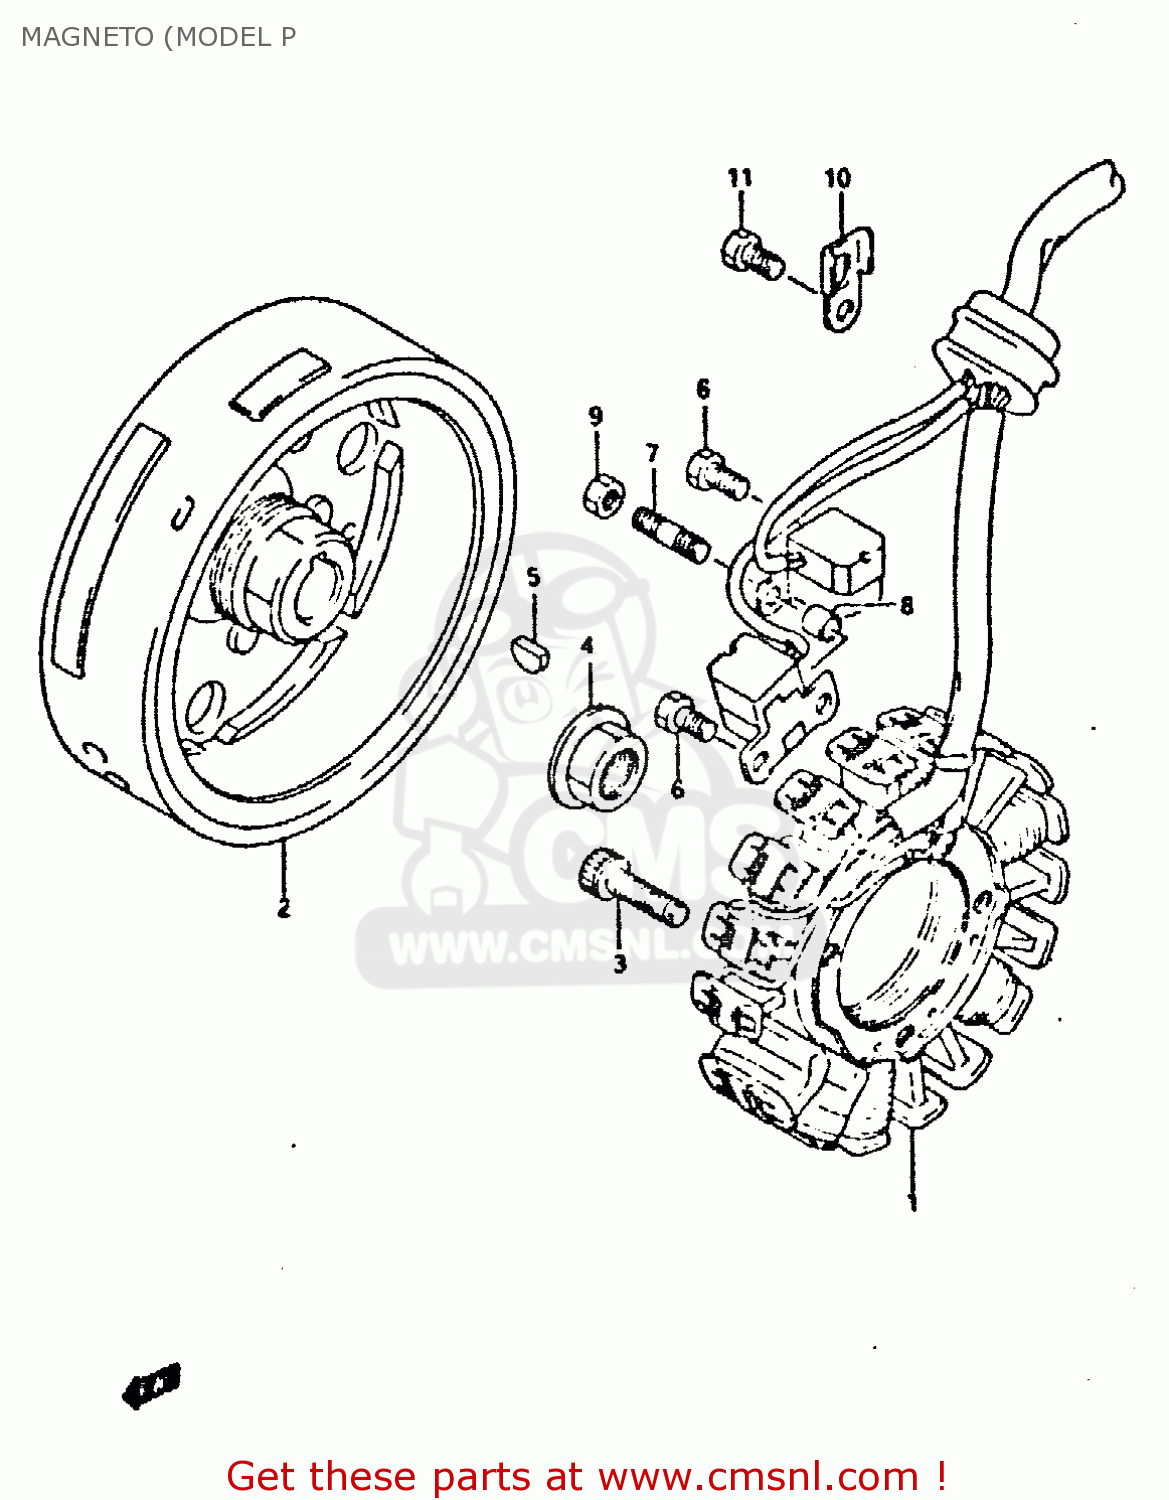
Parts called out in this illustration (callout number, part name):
1	STARTER ASSY
2	ROTOR
3	BOLT
4	NUT
5	KEY
6	BOLT(5X10)
7	BOLT,STUD(5X18)
8	SPACER (5.5X9.5X6.5)
9	NUT
10	CLAMP,GENERATOR LEAD WIRE
11	BOLT(5X10)
